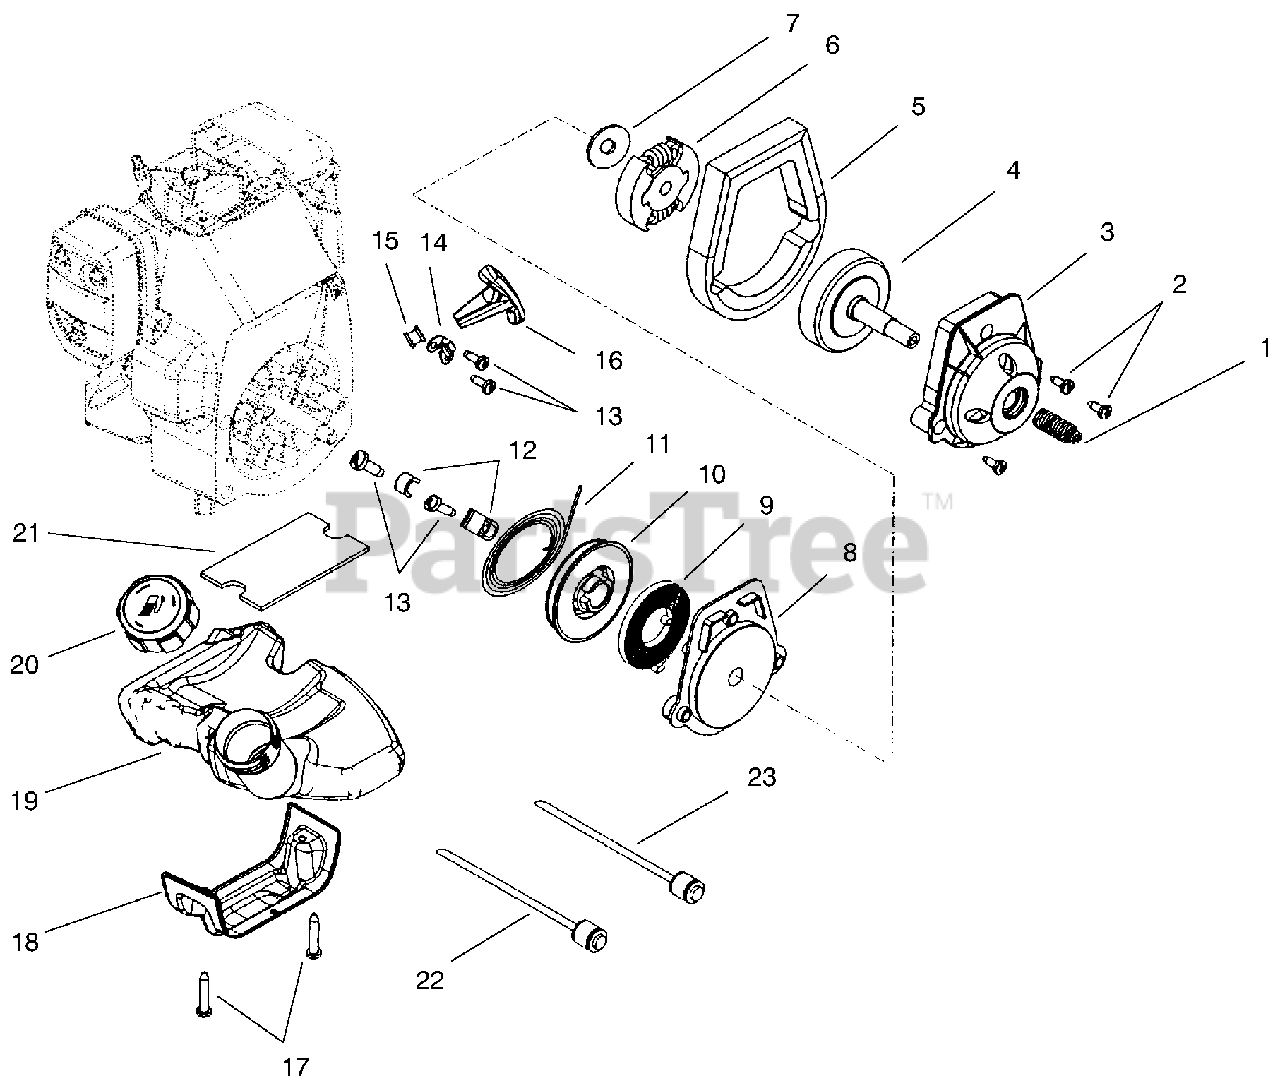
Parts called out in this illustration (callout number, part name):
1	Spring-Compression
3	Housing-Clutch
4	Drum-Clutch
5	Isolator
7	Washer-Clutch
8	Clutch Housing Assembly W/Drum (Incl. Ref. #3 & 4)
9	Spring-Starter
10	Pulley-Starter
11	Rope-Starter
12	Retainer-Starter Pulley
13	Screw
14	Retainer-Rope Guide
15	Guide-Rope
16	Handle-Starter
17	Screw-Fuel Tank Bracket
18	Bracket-Fuel Tank
19	Tank-Fuel (Incl. Ref. #20, 22 & 23)
20	Cap-Fuel
21	Pad-Fuel Tank
22	Fuel Line Assembly W/Filter
23	Line-Fuel Return
